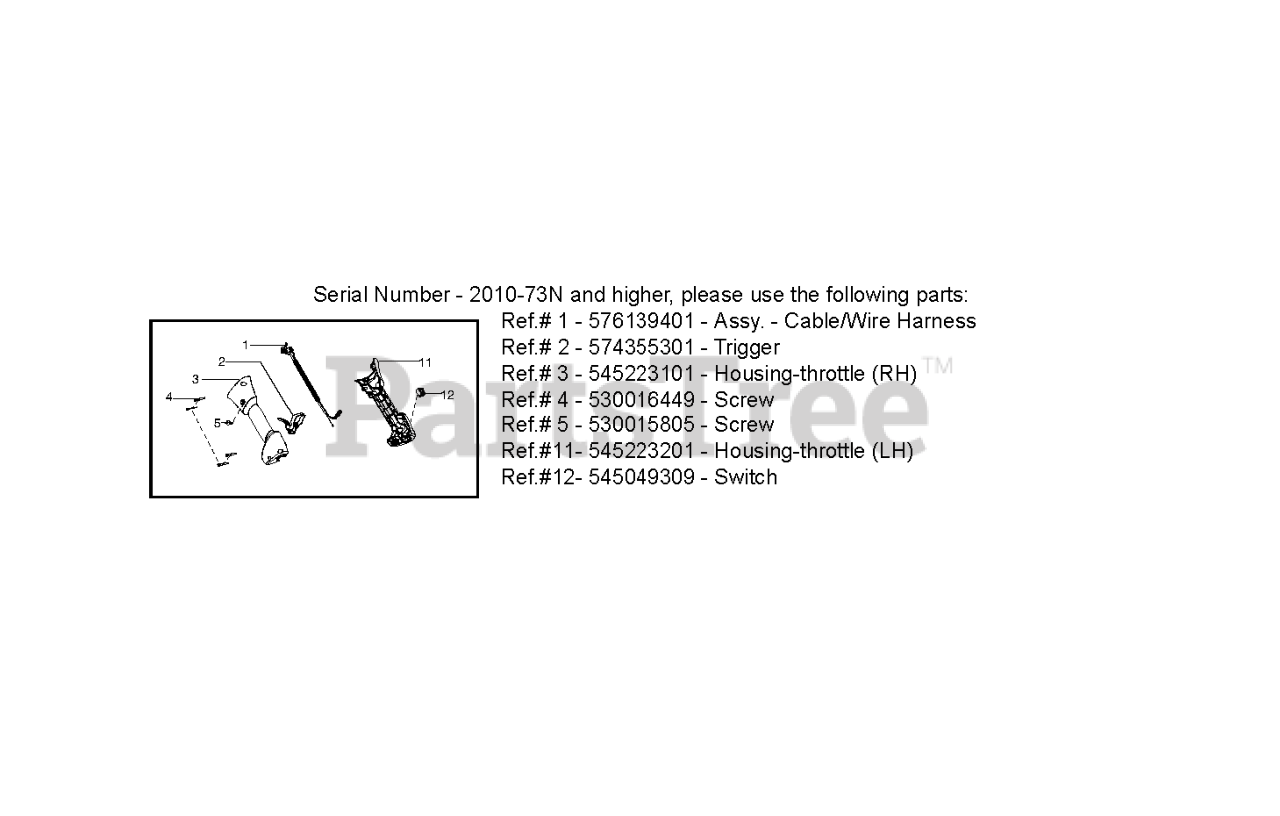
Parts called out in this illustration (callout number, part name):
1	ASSY CABLE / WIRE HARNESS
2	TRIGGER THROTTLE HVA ORANGE
3	HSG THROTTLE RIGHT NL HVA
4	SCREW M4 X 1.75 PT 16MM
5	SCREW-10-14 X 1/2 PLASTITE
11	HSG THROTTLE LEFT HVA
12	SWITCH
